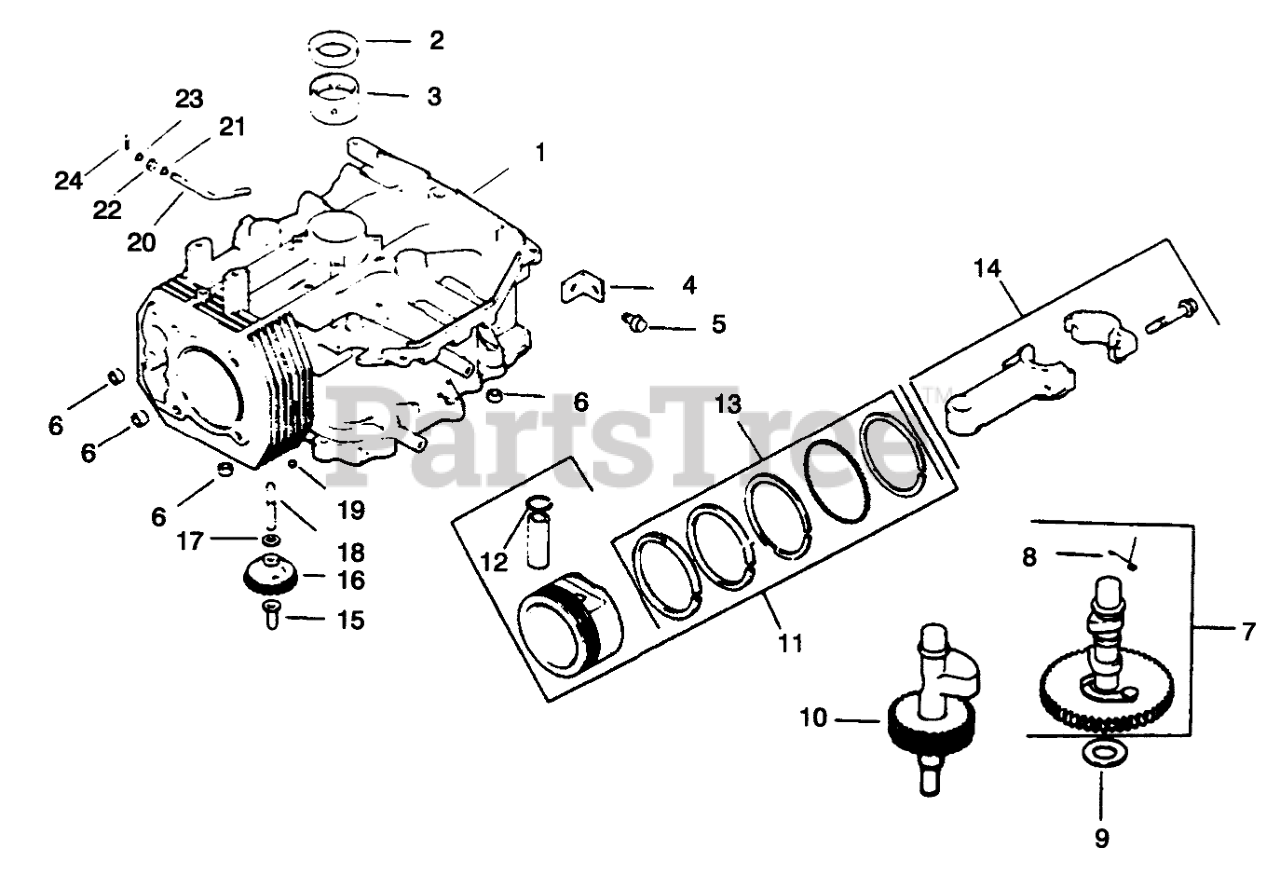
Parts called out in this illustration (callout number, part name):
1	Short Block
2	Seal-Crankshaft
3	Bearing-Crankshaft(Std.)
4	Strap-Lifting
5	Screw
6	Pin-Dowel
7	Camshaft Assembly
8	Spring-Actuating
9	Shim-Camshaft
10	Shaft-Balance
11	Set Piston w/Ring STD
12	Retainer-Piston Pin
13	Ring Set STD
14	Connecting Rod STD
15	Pin-Governor
16	Gear, governor
18	Shaft-Gear, Governor
19	Plug
20	Shaft-Governor Cross
21	Washer
22	Seal-Cross Shaft
24	Pin-Hitch
